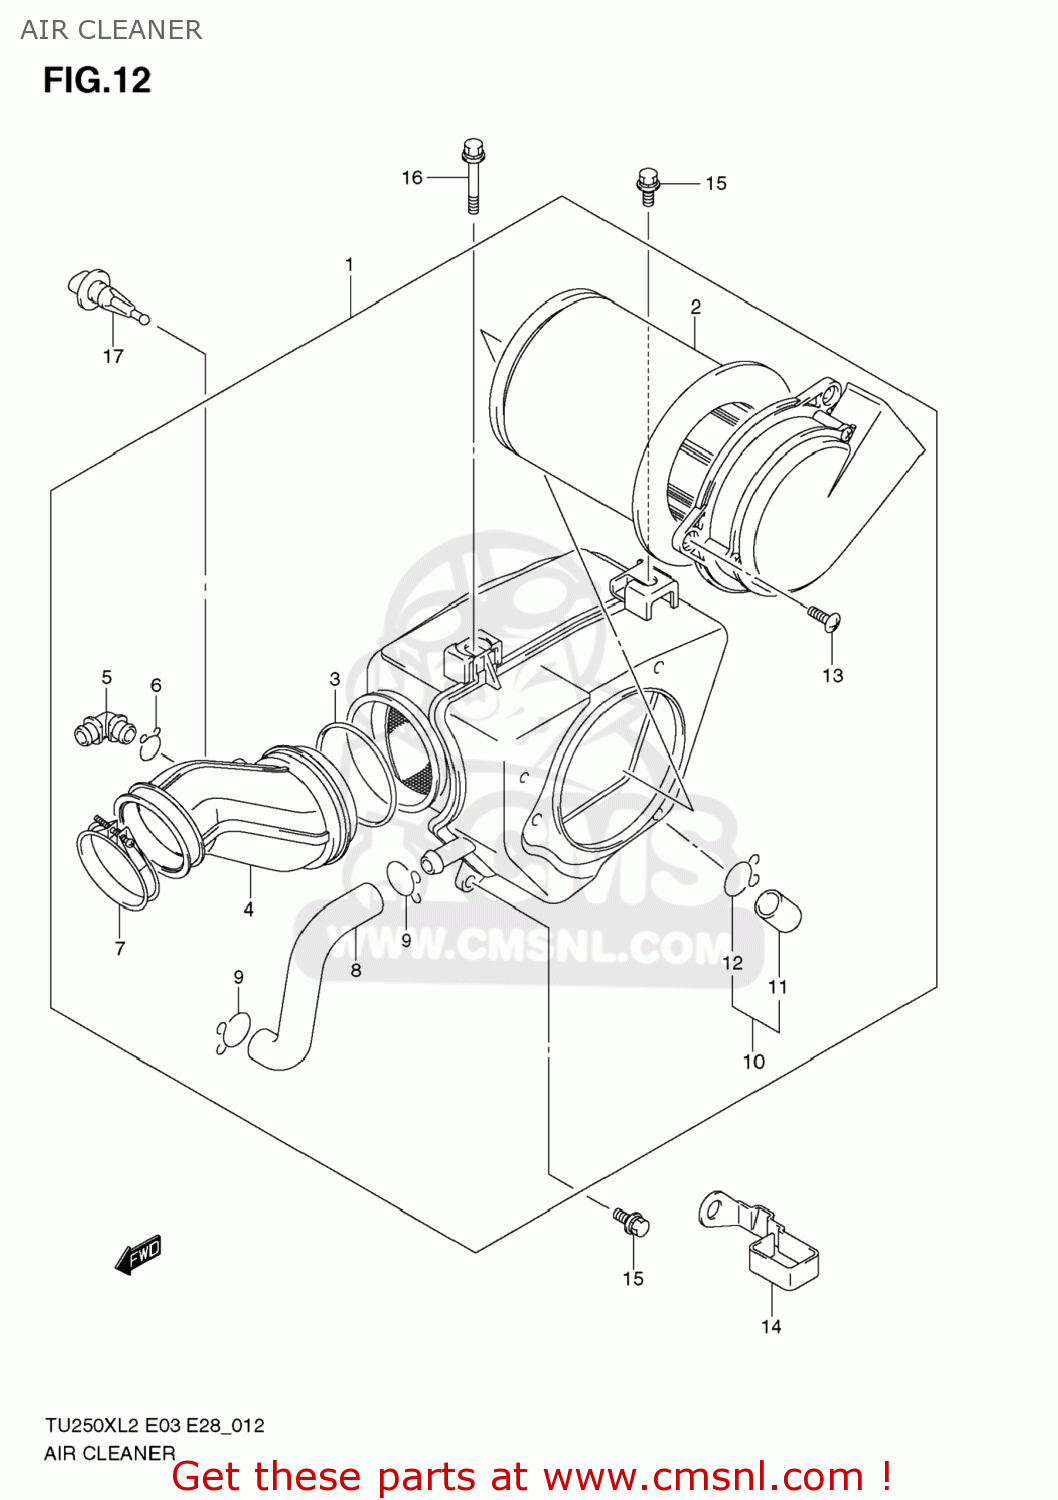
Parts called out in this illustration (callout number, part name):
1	CLEANER ASSY,AIR
2	FILTER
3	CLAMP,AIR CLEANER SIDE
4	TUBE,OUTLET
5	JOINT
6	CLIP
7	CLAMP
8	TUBE,BREATHER
9	CLIP
10	PLUG ASSY,DRAIN
11	PLUG
12	CLIP
13	SCREW
14	CLAMP,AIR CLEANER DRAIN TUBE
15	BOLT
16	BOLT
17	SENSOR,INLET AIR TEMP
